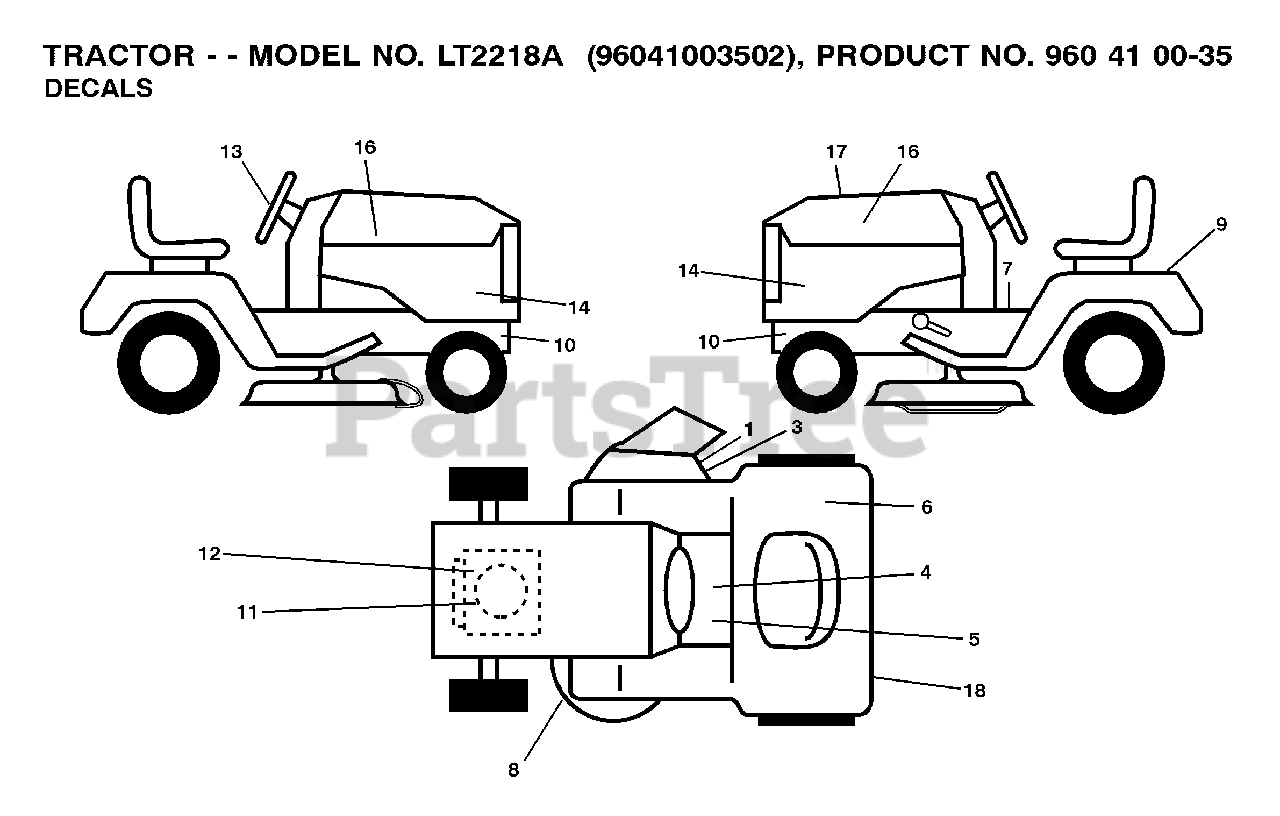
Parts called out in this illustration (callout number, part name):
3	DECAL, DEFLECT WARNING
5	DECAL V BELT SCHEMATIC
8	DECAL.INTERNATIONL.CUTFINGER
9	DECAL BTRY SYMBOLS
19	DECAL PARK BRAKE
